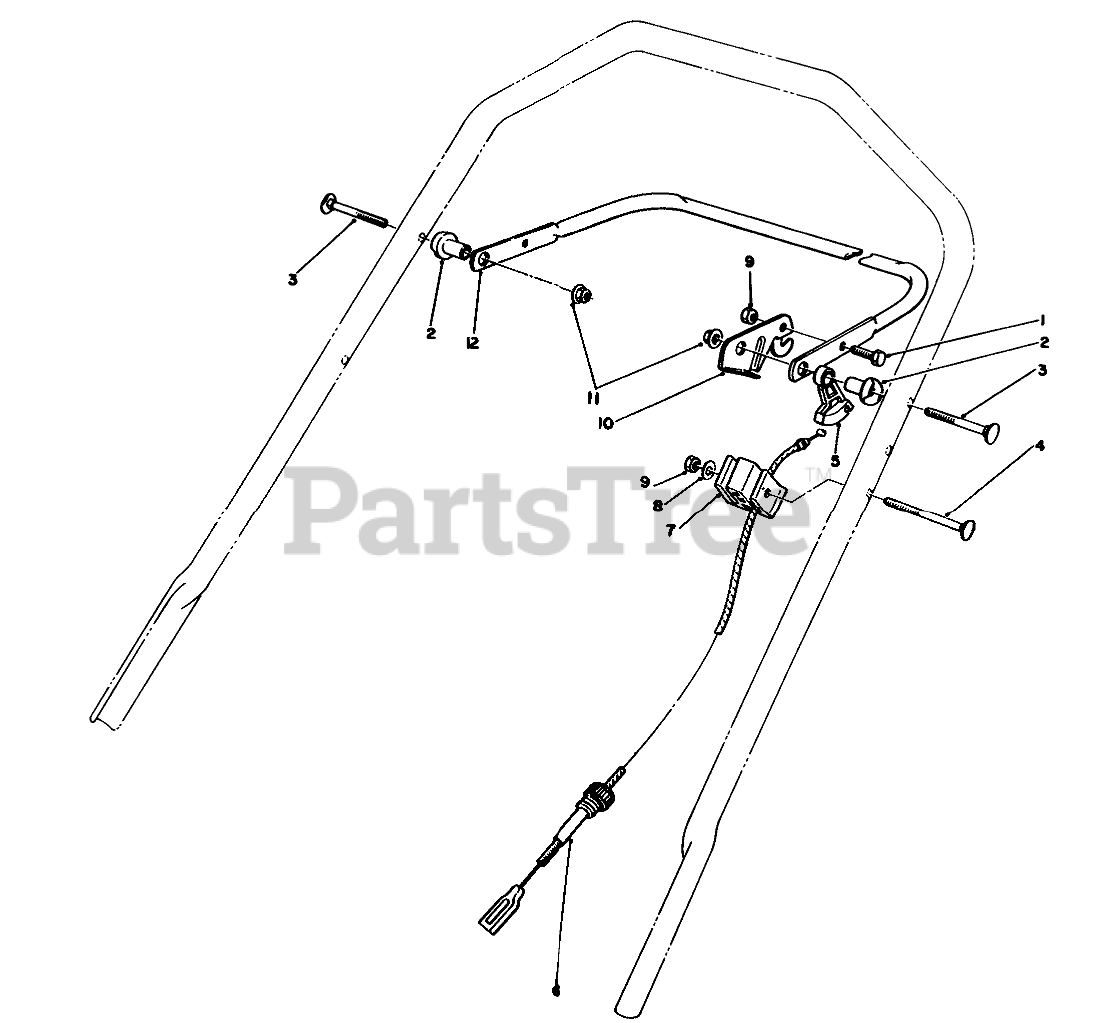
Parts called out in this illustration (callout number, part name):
1	SCREW-HH
2	SPACER-SUPPORT
3	5/16-18 X 2 HNDLE SCREW
4	HANDLE SCREW
5	LEVER-TRACTION
6	CABLE-TRACTION
7	SUPPORT-CABLE
8	WASHER-FLAT
9	NUT-LOCK, NI
10	CONTROL LEVER
11	NUT-LOCK, NI
12	Bar-Control
